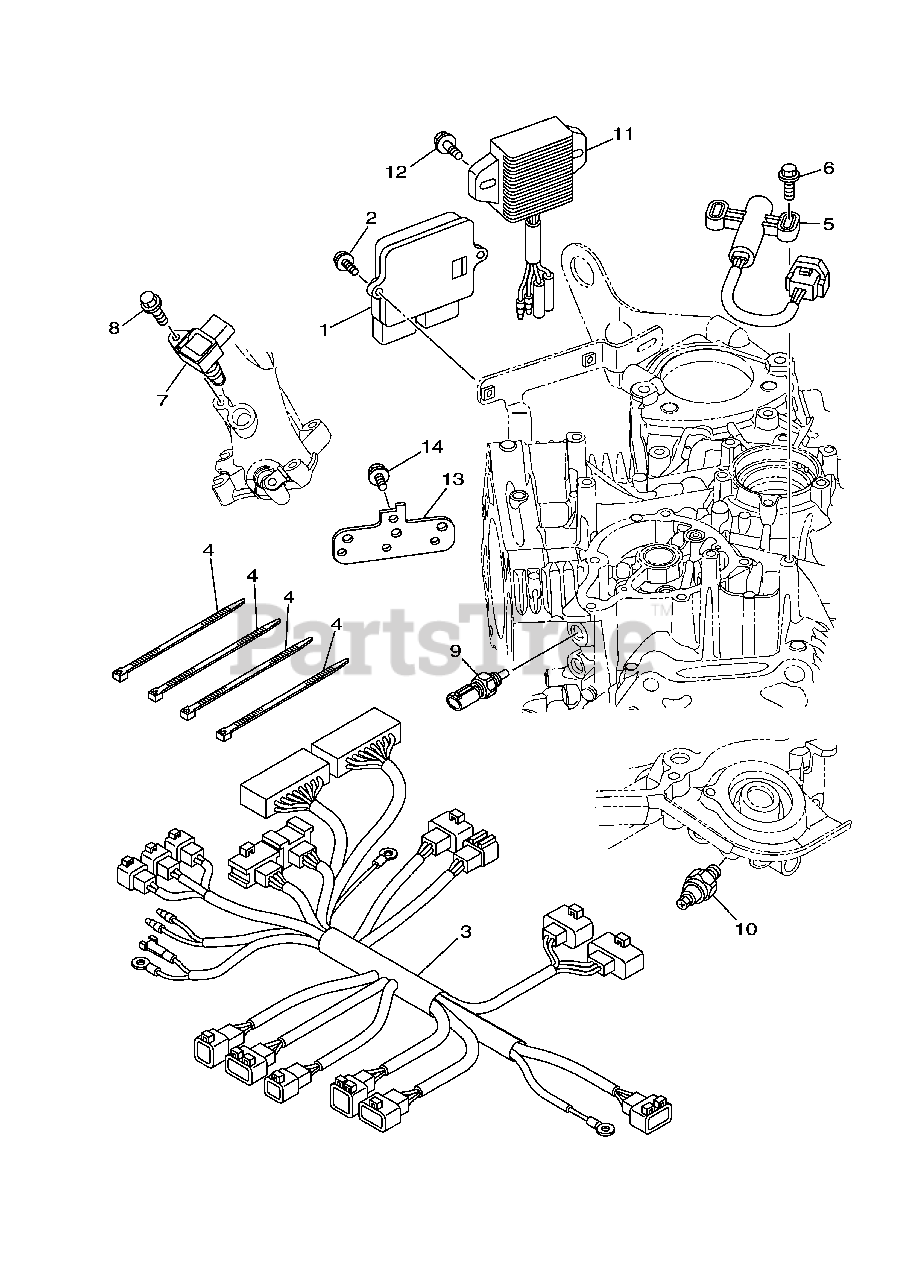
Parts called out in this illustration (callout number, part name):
1	ENGINE CONTROL UNIT ASSY
2	BOLT, FLANGE
3	WIRE, LEAD
5	CRANK POSITION SENSOR
6	BOLT, FLANGE
7	SENSOR, PRESSURE
8	BOLT, FLANGE
10	OIL PRESSURE SWITCH ASSY
11	RECTIFIER & REGULATOR ASSY
12	BOLT, FLANGE
14	BOLT, FLANGE
